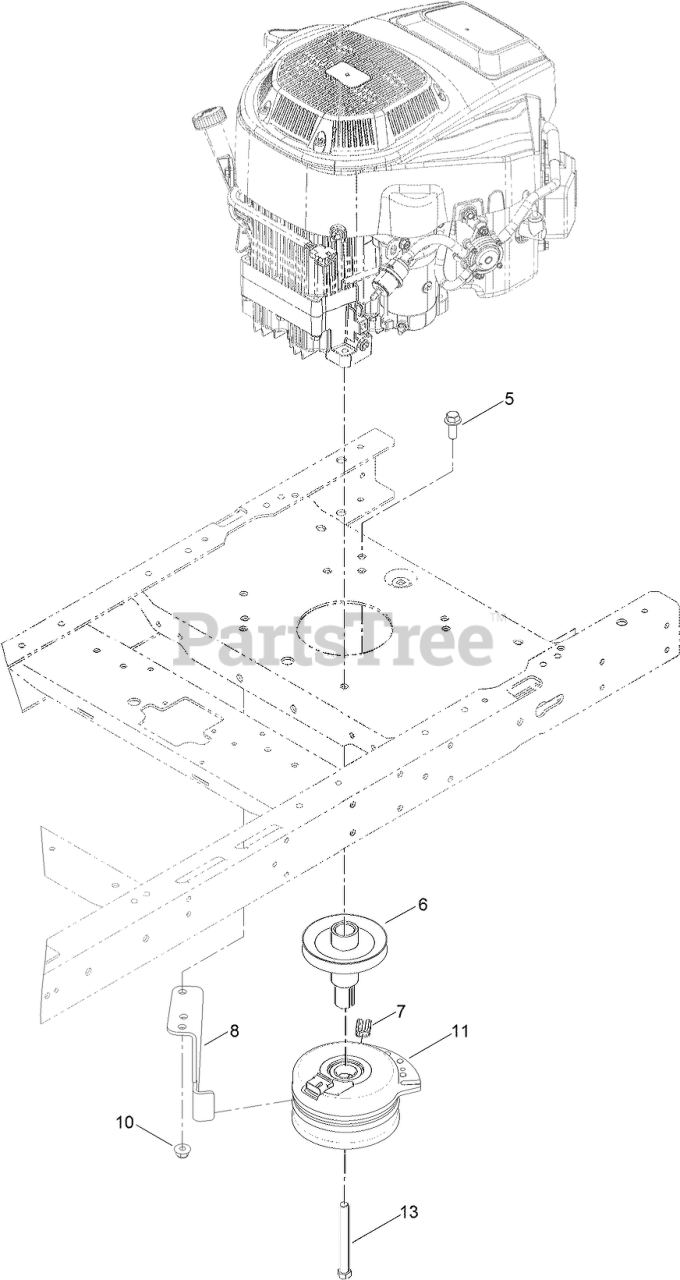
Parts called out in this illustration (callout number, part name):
5	SCREW-HHF
6	PULLEY-ENGINE
7	ISOLATOR-CLUTCH
8	STOP-CLUTCH
10	NUT-HF, NI
11	CLUTCH-ELECTRIC
13	SCREW-HH
